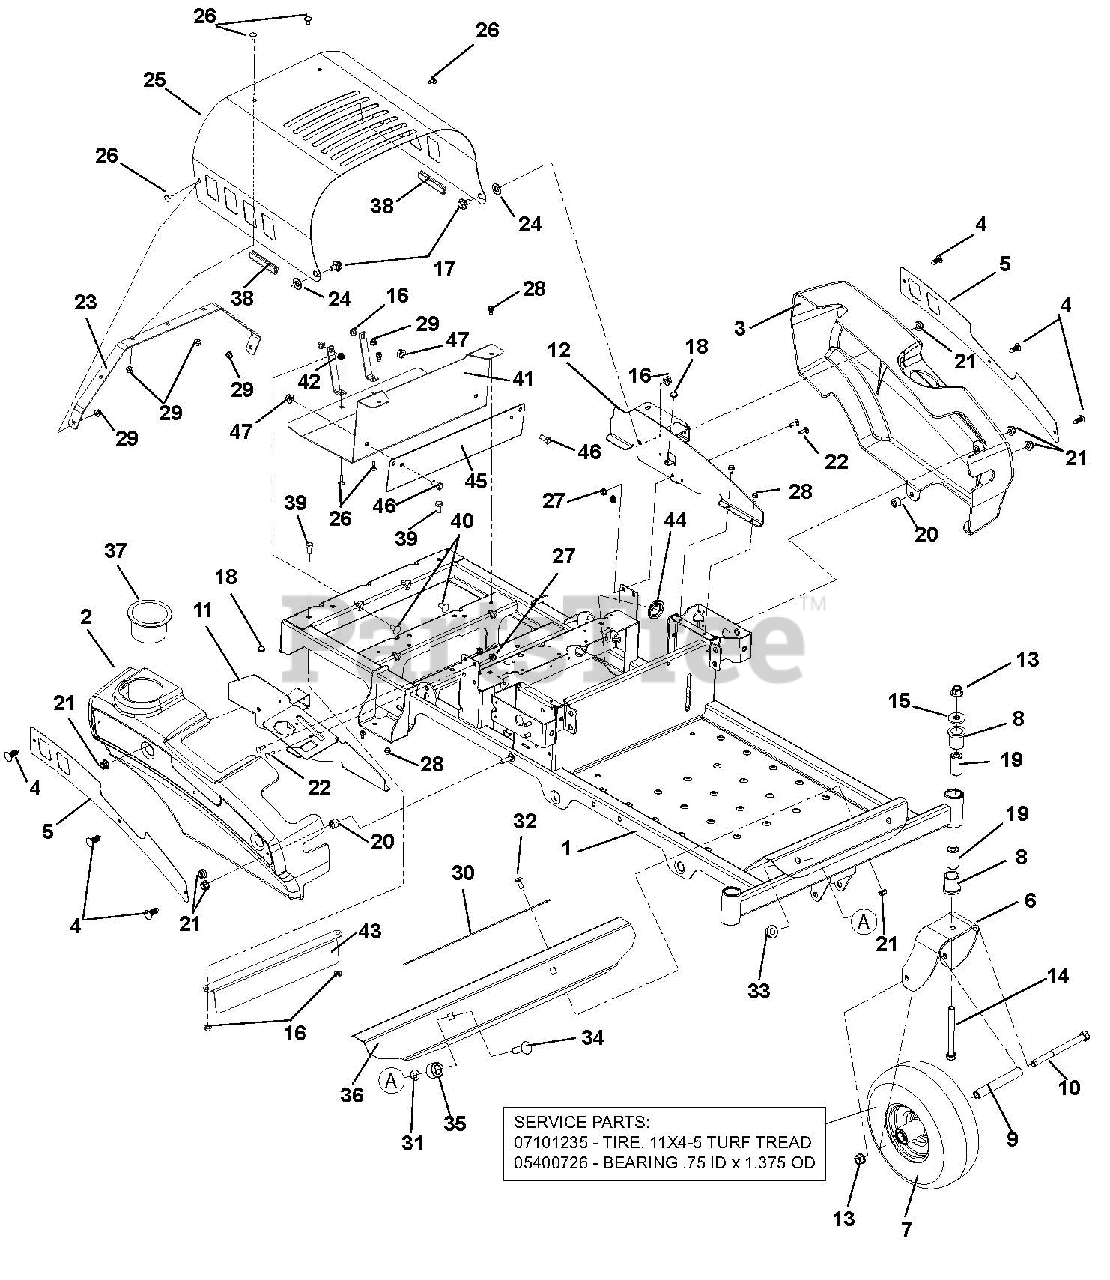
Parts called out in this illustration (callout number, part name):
1	KIT, ZOOM/ZT FRAME W/ DECALS
2	FENDER, RH
3	KIT, LH FENDER W/ DECAL ZOOM
4	RIVET, .25 NYLON PANEL
5	PLATE, FENDER
6	WMT, CASTER FORK
7	ASM, WHL/TIRE 11X4.00-5
7	TIRE, 11X4-5 TURF TREAD
7	BRG, .75 ID X 1.375 OD
8	BSHG-FLG 1.00X1.25X1.50X1.50
9	SPACER, ROLLED WHEEL
10	BLT, HEX .50-13X6.50 GR5 ZCC
11	WLDMT, RH FENDER MOUNT
12	WLDMT, LH FENDER MOUNT
13	@NUT-LK-TOP-FLG .50-13 YWZC
14	BLT, HEX .50-13X5.00 GR5 ZCC
15	WSHR-FL-STL.511X1.441X.125 YWZ
16	@NUT-LK-TOP-FLG .38-16 YWZC
17	BOLT-SHLDR .375-16X.150
18	BUMPER GROMMET
19	SPACER, CASTER .50X1.00X1.84
20	BSHG-SLV .391X.688X.52 PM
21	@NUT-LK-NYL-FLG .31-18 YWZC
22	BLT, RHSN .25-20X.750 G5 ZCC
23	BRACE, HOOD
24	WSHR-FL-NYL .518X1.000X.080
25	HOOD, ZOOM
26	@BLT-RDHDSQNK .25-20X.50 G5YZ
27	NUT,NYL-FLG .25-20 GF ZCC
28	SCR-TAP .25-20X.50 HWH ZCC
29	@NUT-LK-TOP-FLG .25-20 YWZC
30	GRIP, ADHESIVE (1" X 16" BLK)
31	NUT-PUSH, .50
32	@BLT-RHDSSQNK .31-18X.75 G5YZ
33	@NUT-LK-NYL-FLG .50-13 YWZC
34	@BLT-RDHDSQNK .50-13X1.75 G5YZ
35	WMT, UPPER CONTROL ARM
36	FOOTREST
37	CUPHOLDER, SNAP-IN 3.75OD
38	EDGING, CLUTCH PADDLE - 2.00"
39	@BLT-HEX .38-16X1.00 GR5 YWZC
40	@BLT-RDHDSQNK .38-16X1.00 G5YZ
41	GUARD, HEAT SHIELD (ZOOM/ZT)
42	STRAP, HEAT SHIELD (ZOOM/ZT)
43	GUARD, HOT SURFACE (ZOOM/ZT)
44	GROMMET 1.0ID X 1.38 OD
45	GUARD, REAR CLUTCH
46	BLT, HEX .31-18X.50 GR5 ZCC
47	NUT-LK-TOP-FLG .312-18 GF ZCC
